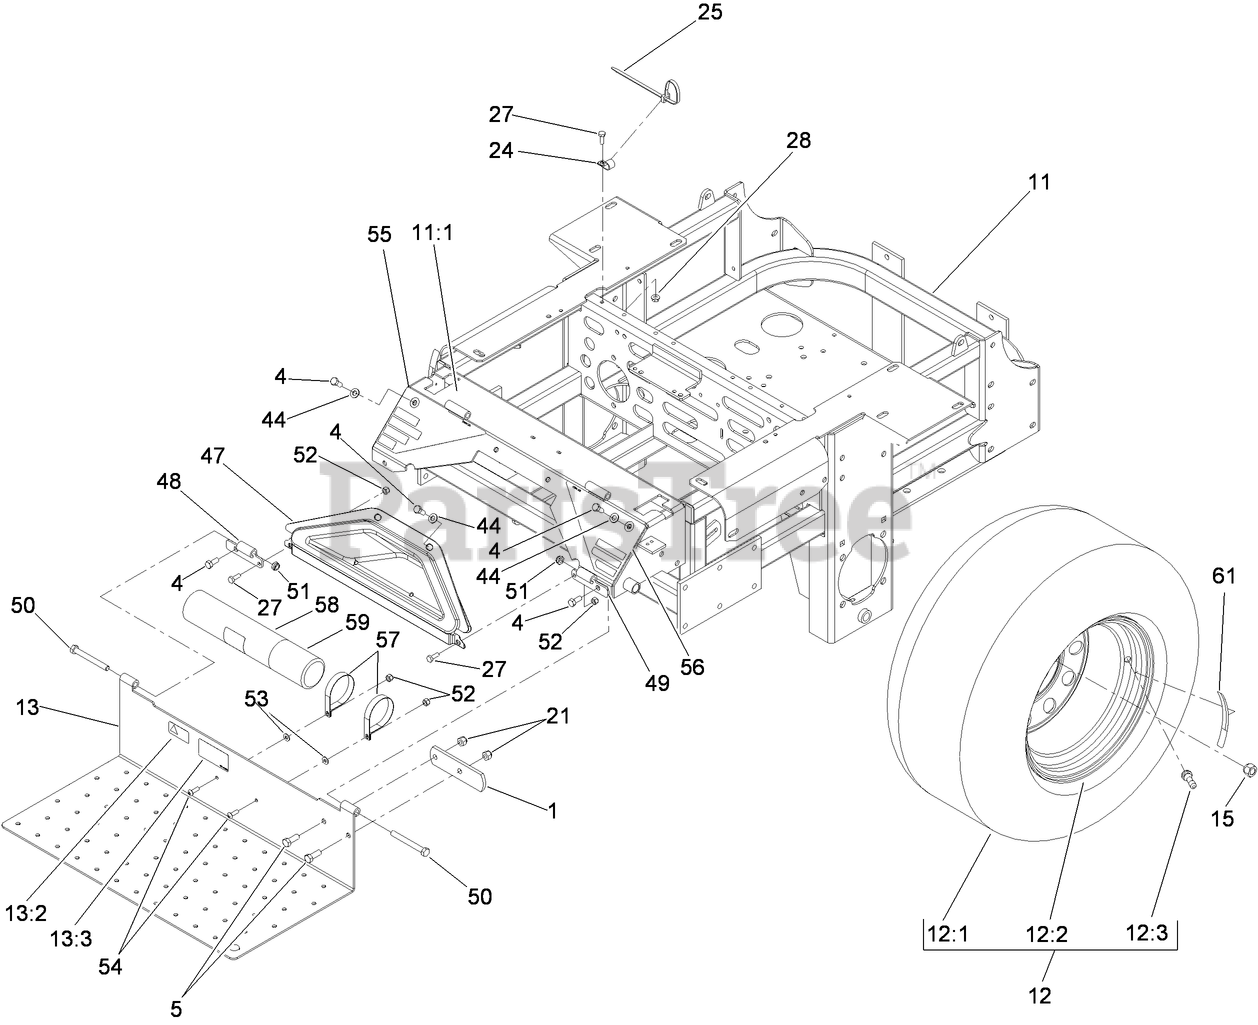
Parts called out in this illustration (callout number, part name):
1	STOP-BRAKE, PARK
4	SCREW-HH
5	SCREW-HH
11	FRAME ASM
11:1	DECAL-CONSOLE, TOP
12	WHEEL AND TIRE ASM
12:1	TIRE
12:3	STEM-VALVE
13	FLOORPAN
13:2	DECAL-PROTECTION, EAR
13:3	Decal-Location, Manual
15	NUT-LUG
21	NUT-LOCK, NI
24	CLIP-LOOM
25	TIE-PLASTIC
27	SCREW-HH
28	NUT-HF
44	WASHER-FLAT
47	Pocket
48	Hinge-Floorpan, LH
49	Hinge-Floorpan, RH
50	SCREW-HH
51	NUT-LOCK, NI
52	NUT-LOCK, NI
53	WASHER-FLAT
54	SCREW-PRH
55	Decal-Warning
56	Decal-Danger
57	R-Clamp
58	TUBE-MANUAL
59	CAP-HOUSING
61	DECAL
